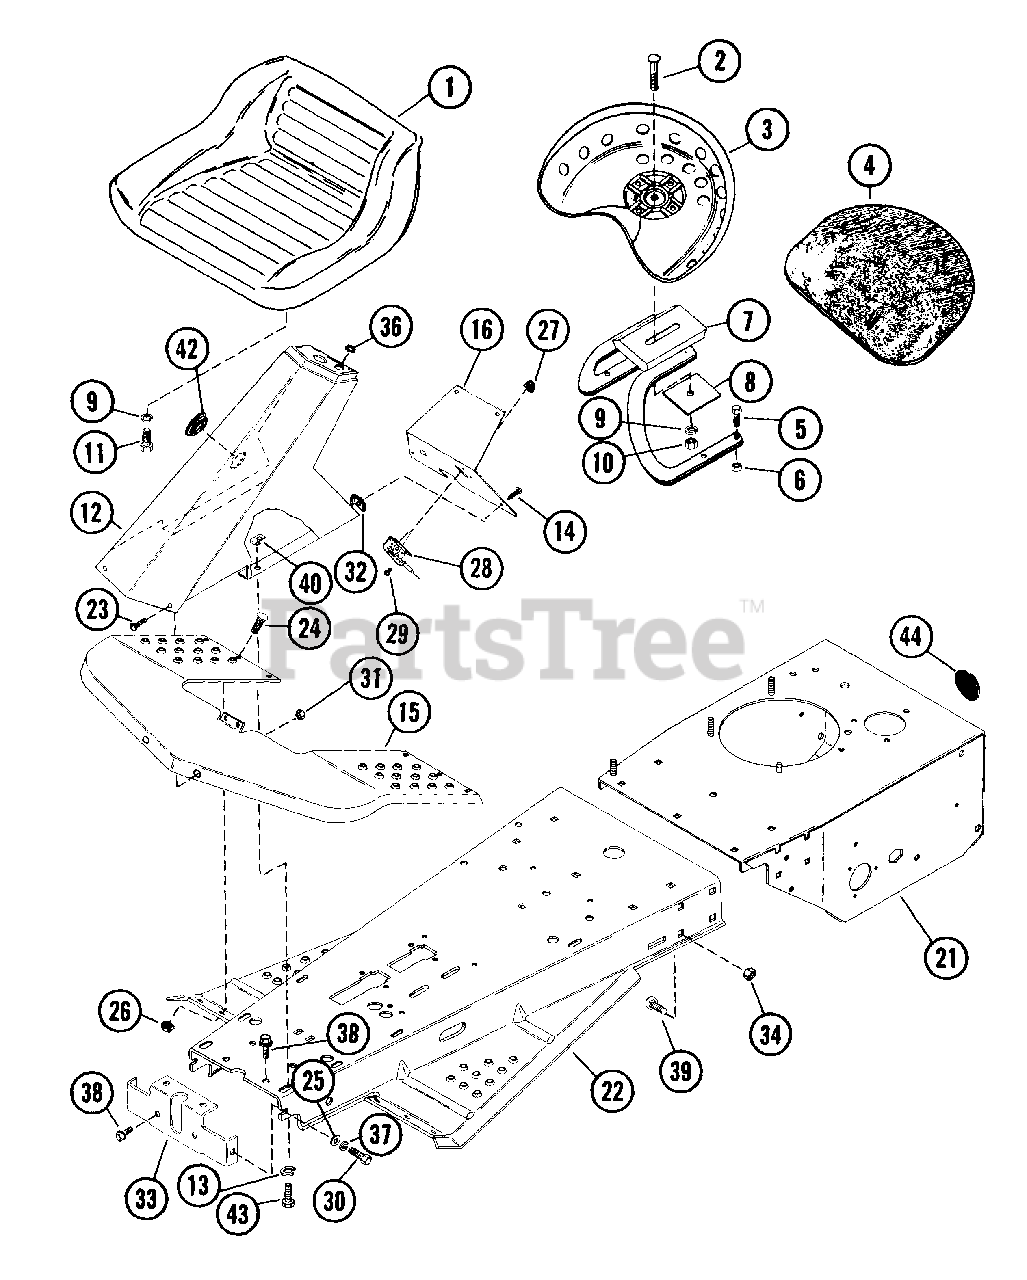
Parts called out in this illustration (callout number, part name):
1	SEAT
2	BLT-RDHDSQNK .50-13X1.25 PL
3	SEAT
4	SEAT COVER
5	BLT-HEX .31-18X1.50 PL GR2
6	NUT-LK .312-18 GR A PL
7	SEAT BRACKET
8	SEAT SUPPORT WASHER
9	WSHR-LK .500X.151 HVY PL
10	NUT .50-13 PL
11	BLT-HEX .50-13X1.25 PL GR2
12	STEERING COLUMN
13	WSHR-LK-INT .313X.030 PL
14	SCR-TAP 10-12X.50 CRPH PL A
15	FRONT FENDER
16	DASH PANEL ASSEMBLY
21	REAR FRAME
22	FRONT FRAME ASSEMBLY
23	SCR-MCH 10-24X.38 SLTOR PAN PL
24	SCR-SLTR-SERNK .25-20X.62 PL
25	WSHR-FL-STL .38X.875X.083 PL
26	NUT-LK-FLG .250-20 PL
28	THROTTLE CONTROL
29	RVT-POP.125 X .294 DOME
30	BLT-HEX .31-18X.75 PL GR2
31	NUT-LK TOP 10-24 PL
32	PLASTIC GROMMET
33	FRONT FRAME SUPPORT
34	NUT-FLG. .312-18 PL
36	GROMMET, .31 ID
37	WSHR-LK .312X.097 PL HVY
38	BLT-LK .31-18X.75 GR 5
39	BLT-RDHDSQNK .31-18X.75 GR5 PL
40	NUT-SPEED U-TY .312-18
43	BLT-HEX .31-18X.75 PL GR2
